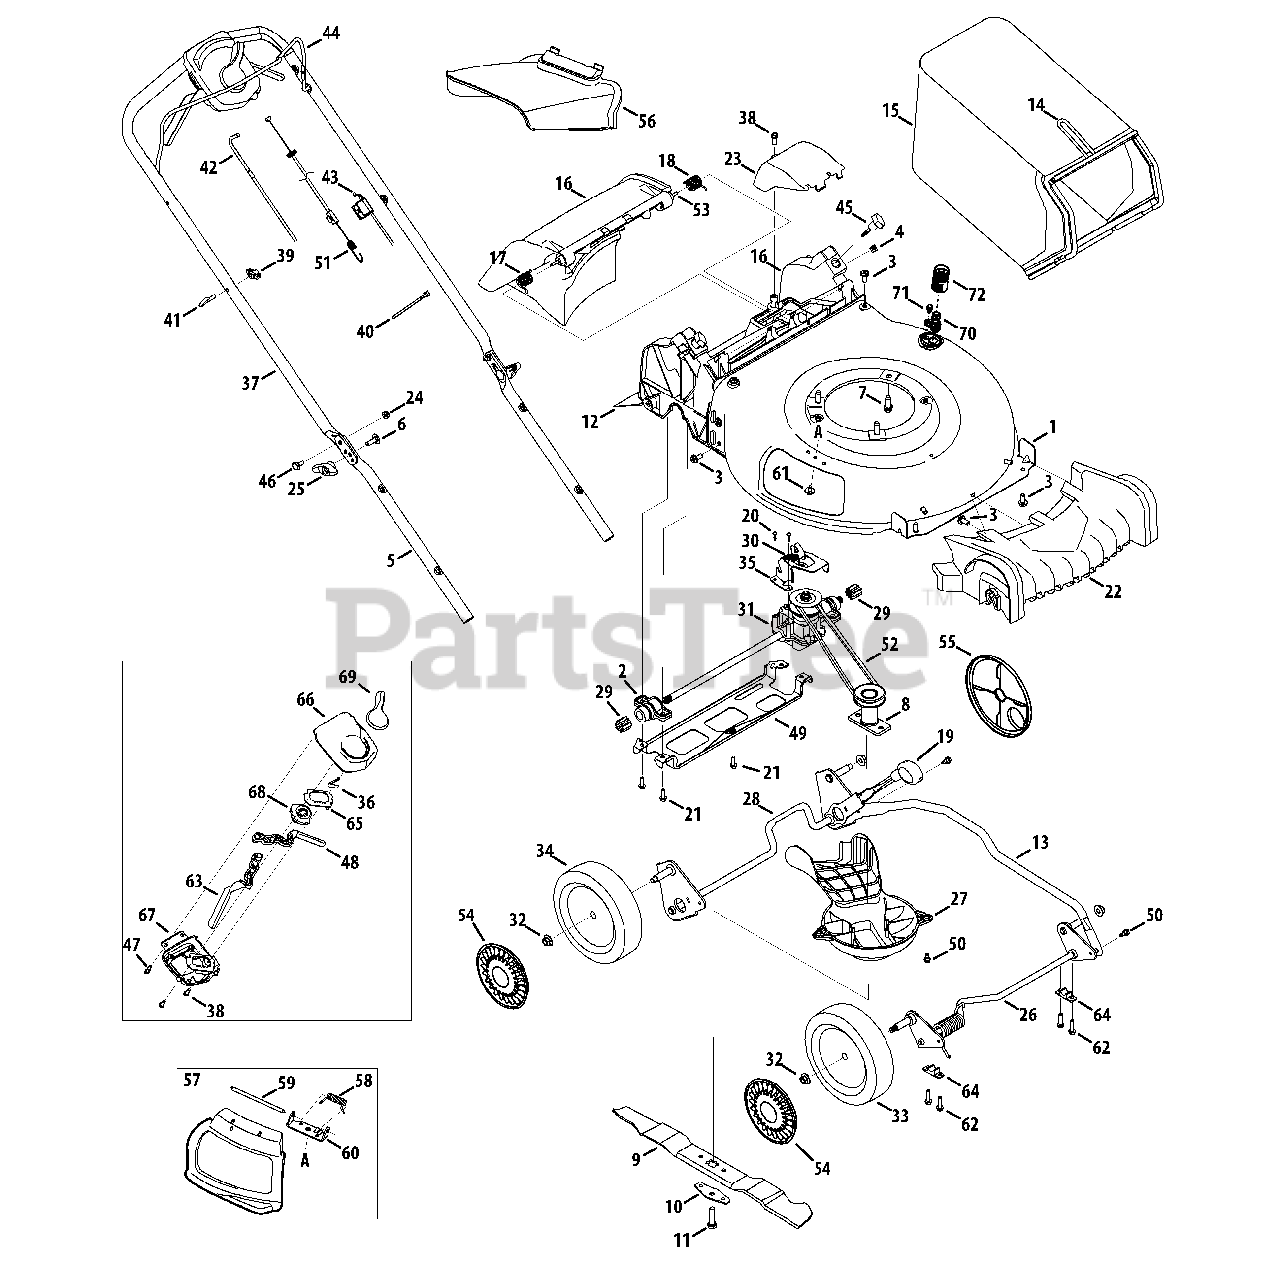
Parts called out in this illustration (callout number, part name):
1	Deck , 21"
2	Bearing Assembly
3	Screw, 5/16-14 x .750
4	Nut, Sq., 1/4-20
5	Lower Handle
6	Carriage Screw ,5/16-18
7	Screw, 3/8-16 x 1.00
8	Blade Adapter
9	Mulching Blade
10	Blade Bell Support
11	Screw, 3/8-24 x 1.50
12	Trailing Shield
14	Grass Catcher Frame
15	Grass Bag
16	Rear Discharge Door Assembly
17	Torsion Spring - RH
18	Torsion Spring - LH
19	Adjustment Lever Knob
20	Screw, .159 x .43 Hex Washer
21	Screw, 1/4-15 x 1.25
22	Front Cover
23	Transmission Cover
24	Nut, Flange Lock, 1/4-20
25	Wing Knob
26	Front Axle Assembly
27	Engine Baffle
28	Rear Axle Assembly
29	Spur Gear, 10T
30	Exten. Spring, 2.675
31	Transmission Assembly
32	Flange Lock Nut, 3/8-16
33	Front Wheel
34	Rear Wheel
36	Spring
38	Screw, 1/4-15 x .750
40	Cable Tie
41	Rope Guide
42	Drive Cable
43	Control Cable
45	Wing Nut
46	Sldr. Screw, .375 x .126 x 1/4-20
47	Scr., Shldr, 1/4-15 x .970
48	Control Lever LH
49	Rear Support Bracket
50	Scr., Shldr., 1/4-20 x .50
51	Speed Adjustment Cable
52	V-Belt
53	Pivot Rod
54	Hubcap, Grey
55	Wheel Dust Cover
56	Side Discharge Chute
57	Mulch Plug (Incl. 58-60)
58	Torsion Spring
59	Hinge Pin
60	Chute Deflector Bracket
61	Screw, 1/4-20 x .500
62	Screw, 1/4-15 x 1.000
63	Control Lever RH
64	Bushing, Lock, .505 Dia. X .62
65	Cable Adjust Plate
66	Upper Housing
67	Lower Housing
68	Speed Adjust Actuator
69	Speed Select Lever
70	Water Nozzle
71	Scr., Shldr., 1/4-20 x .50
72	Water Nozzle Adapter
